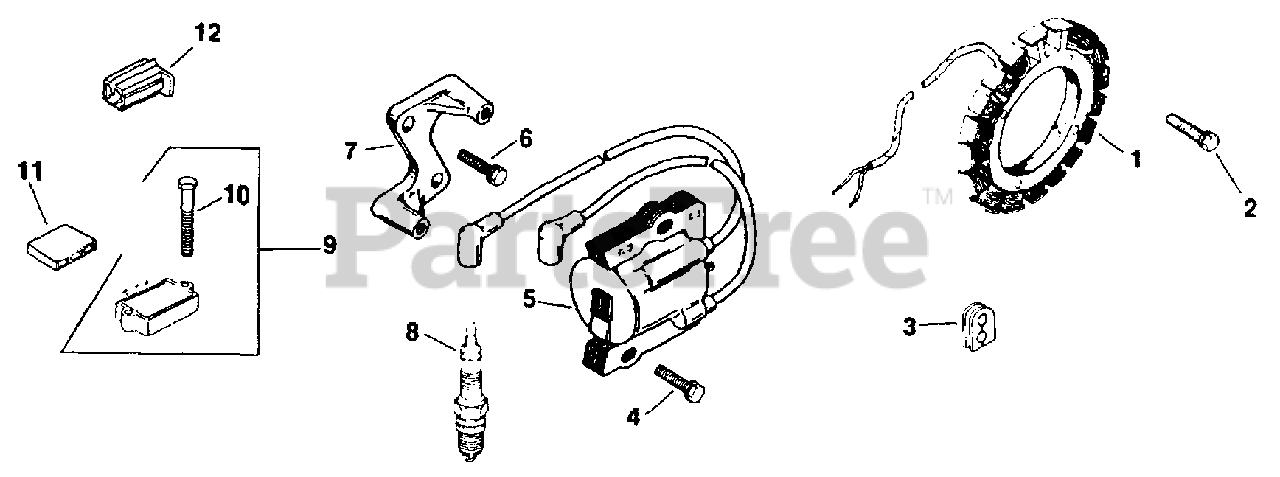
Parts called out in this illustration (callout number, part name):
1	KIT
2	SCREW
3	GROMMET
4	SCREW
5	MODULE, IGNITION
6	SCREW
7	BRACKET, MODULE
8	SPARK PLUG
9	KIT
10	SCREW
11	CONNECTOR
12	CONNECTOR
